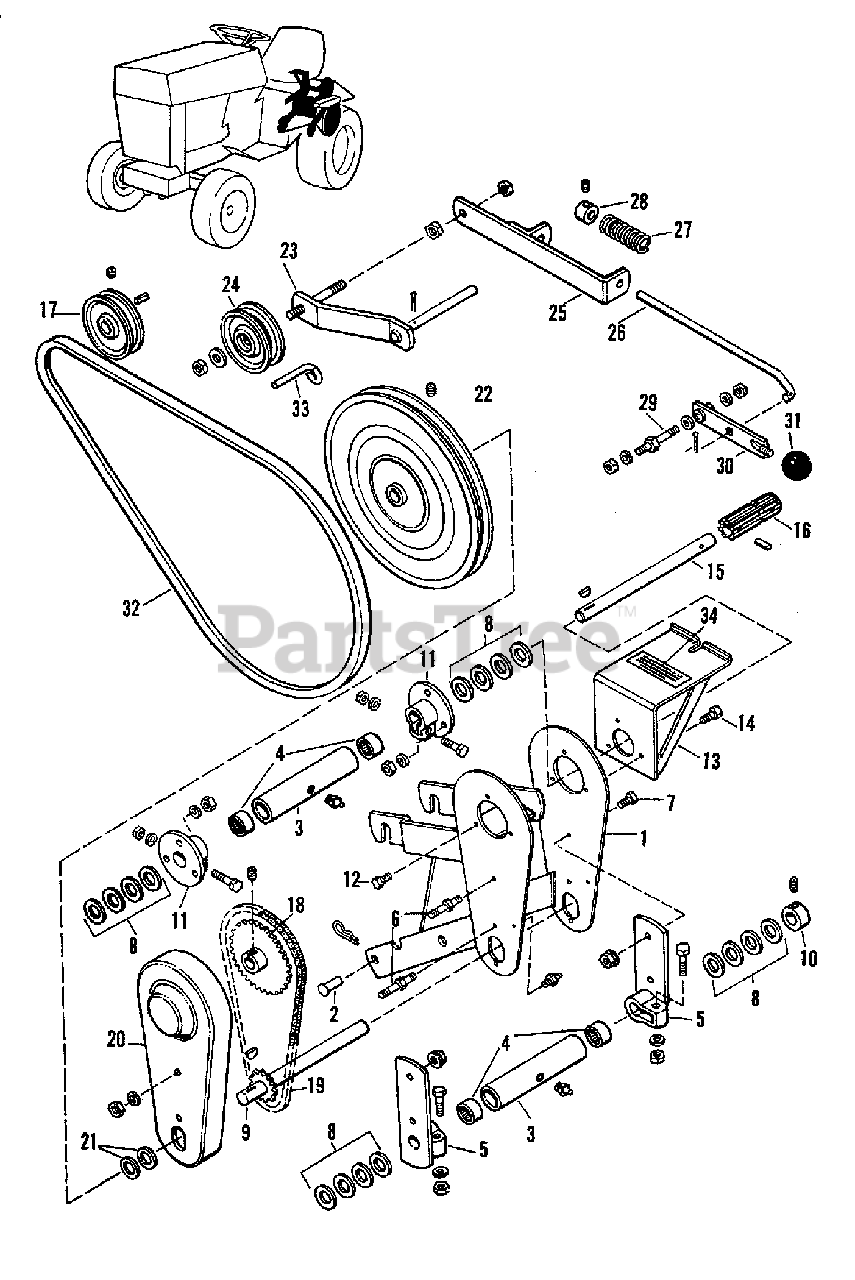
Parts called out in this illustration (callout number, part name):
1	FRAME ASSEMBLY
2	PIN, Round head
2	CLIP, Spring
3	HOUSING, Bearing
3	FITTING, Grease
4	BEARING, Needle
5	SUPPORT, Clamp
5	CAPSCREW, 5/16NC x 1-1/2
5	LOCKWASHER, 5/16
5	NUT, 5/16NC
6	NUT, 3/8NC, Lock
6	LOCKWASHER, 3/8
6	NUT, 3/8NC
7	CAPSCREW, 3/8NC x 3/4
9	SHAFT ASSEMBLY
9	KEY, Woodruff, 3/16 x 3/4
10	COLLAR, Set
10	SETSCREW, 5/16NC x 5/16
11	FLANGE ASSEMBLY
12	CAPSCREW, 5/16NC x 5/8
13	GUARD ASSEMBLY, P.T.O.
14	CAPSCREW, 5/16NC x 3/4
15	SHAFT, P.T.O.
15	KEY, Woodruff, 3/16 x 3/4
16	SHAFT, Spline
16	PIN, Dowel
17	KEY, Woodruff, 3/16 x 3/4
17	SETSCREW, 5/16NC x 5/16
18	SETSCREW, 5/16NC x 5/16
19	CHAIN, w/Connecting Link
20	GUARD, Chain
22	SETSCREW, 5/16NC x 5/16
23	PIVOT ASSEMBLY
23	NUT, Lock, Hex., 3/8NC
23	PIN, Cotter, 1/8 x 1
23	WASHER, 3/8, Standard
24	PULLEY, Idler
25	GUIDE ASSEMBLY, Idler Clutch Rod
26	ROD, Clutch
26	PIN, Cotter, 3/32 x 5/8
28	COLLAR, Set
28	SET SCREW, 1/4NC x 3/8
29	NUT, 5/16NC
29	LOCKWASHER, 5/16
29	WASHER, 5/16
29	NUT, Lock, 5/16NC
30	HANDLE ASSEMBLY
31	BALL, Knob
33	STOP, Belt
34	DECAL, Warning
